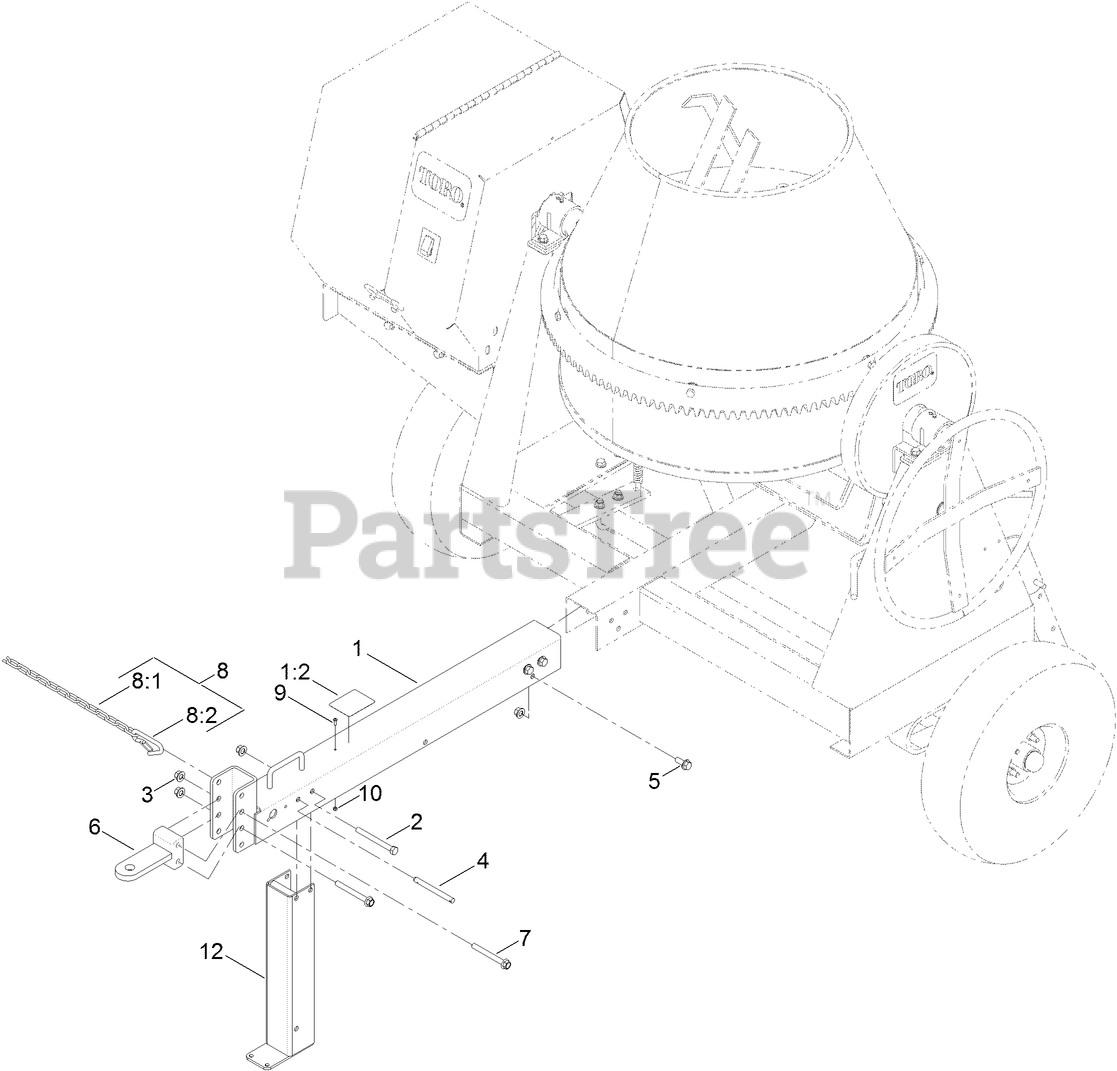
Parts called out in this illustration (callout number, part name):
1	TOW POLE
1:2	DECAL-SAFETY CHAIN, TOWING
2	SCREW-HH
3	NUT-LOCK
4	PIN-CLEVIS, LANYARD
5	SCREW-HHF
6	HITCH-PLATE
7	SCREW-HHF
8	SAFETY CHAIN KIT
8:1	CHAIN-118 INCH
8:2	HOOK-CHAIN, SAFETY LATCH
9	SCREW-PPH
10	NUT-LOCK, NI
12	POST-FOOT
